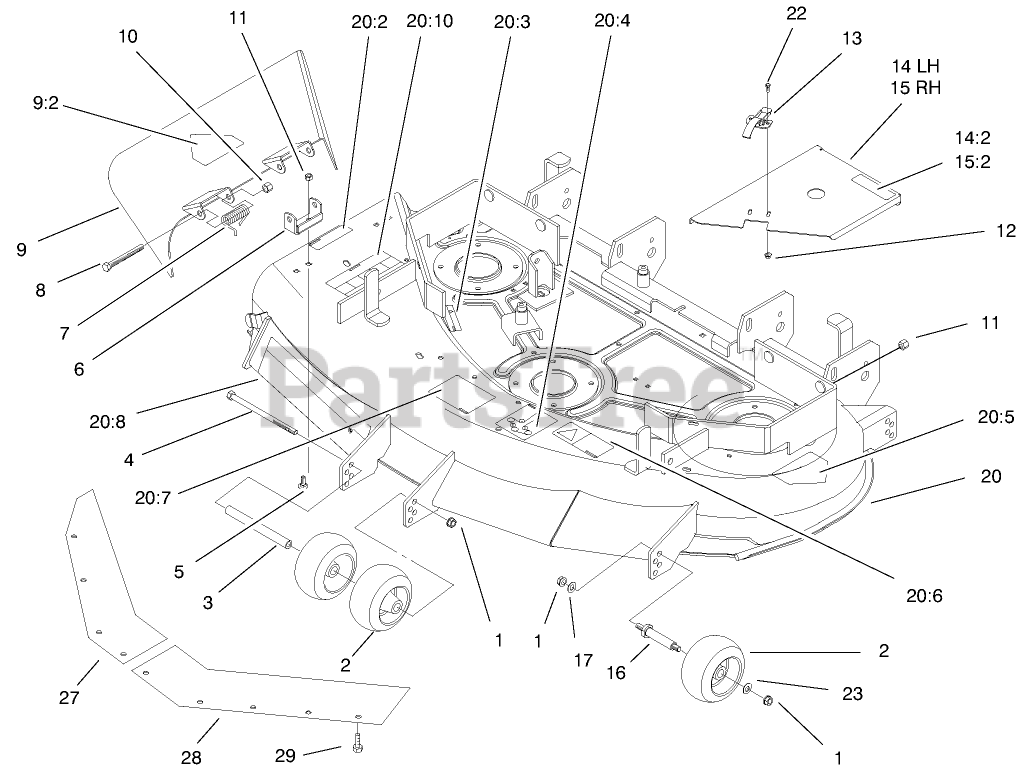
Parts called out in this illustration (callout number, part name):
1	NUT-HHF, WHIZ
2	WHEEL-GAGE
3	SPACER-WHEEL
4	SCREW-HH
5	SCREW-CARR
6	BRACKET-PIVOT
7	SPRING
8	SCREW-HH
9	CHUTE-DISCHARGE
9:2	DECAL-DANGER
10	NUT-HEX
11	NUT-LOCK, CONE
12	NUT-LOCK, FLANGE
13	CLAMP-SLOTTED
14	LH COVER ASM
14:2	DECAL-DANGER
15	RH COVER ASM
15:2	DECAL-DANGER
16	SPACER
17	Washer
20	44" Deck ASM
20:2	DECAL-DANGER
20:3	DECAL-COVER, MISSING
20:4	DECAL-ROUTING, BELT
20:5	DECAL-DANGER
20:6	DECAL-TORQUE, BLADE BOLT
20:7	DECAL-WHEEL, GAGE
20:8	DECAL
20:10	DECAL-DANGER, THROWN OBJECT
22	SCREW-HWH
23	Washer
27	PLATE-BLOWOUT, RH
28	PLATE-BLOWOUT, LH
29	SCREW
